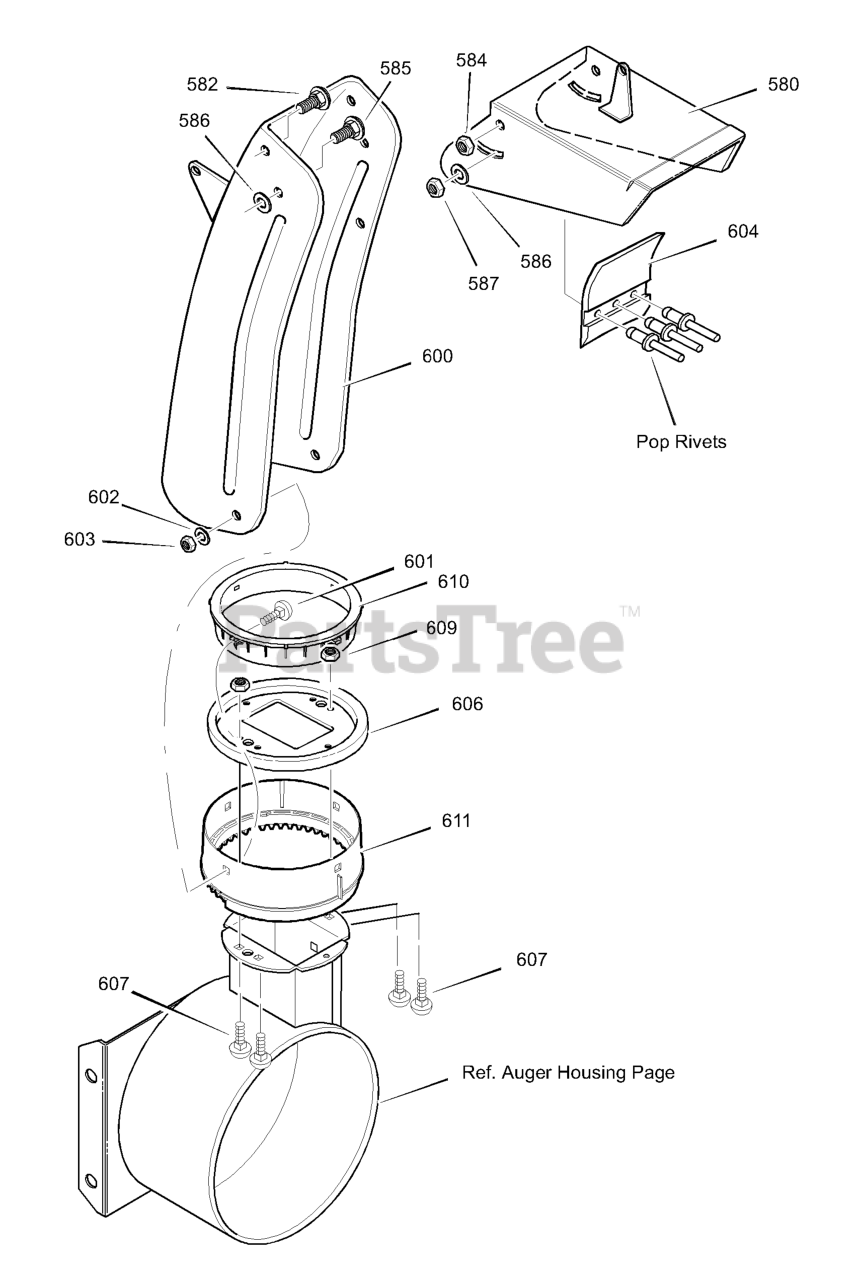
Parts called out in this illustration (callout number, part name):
580	CHUTE, UPPER W/REMOTE
582	SCREW, 5/16-18 x 0.75
584	NUT
585	SCREW, 5/16-18 x 0.75
586	PLASTIC WASHER
587	NUT
600	CHUTE, LOWER W/REMOTE
601	BOLT, 5/16-18 X 1.00 CATT.
602	WASHER, FLAT
603	NUT
606	CHUTE COLLAR
607	BOLT
609	NUT
610	RETAINER, RING INNER
611	RETAINER, RING OUTER
